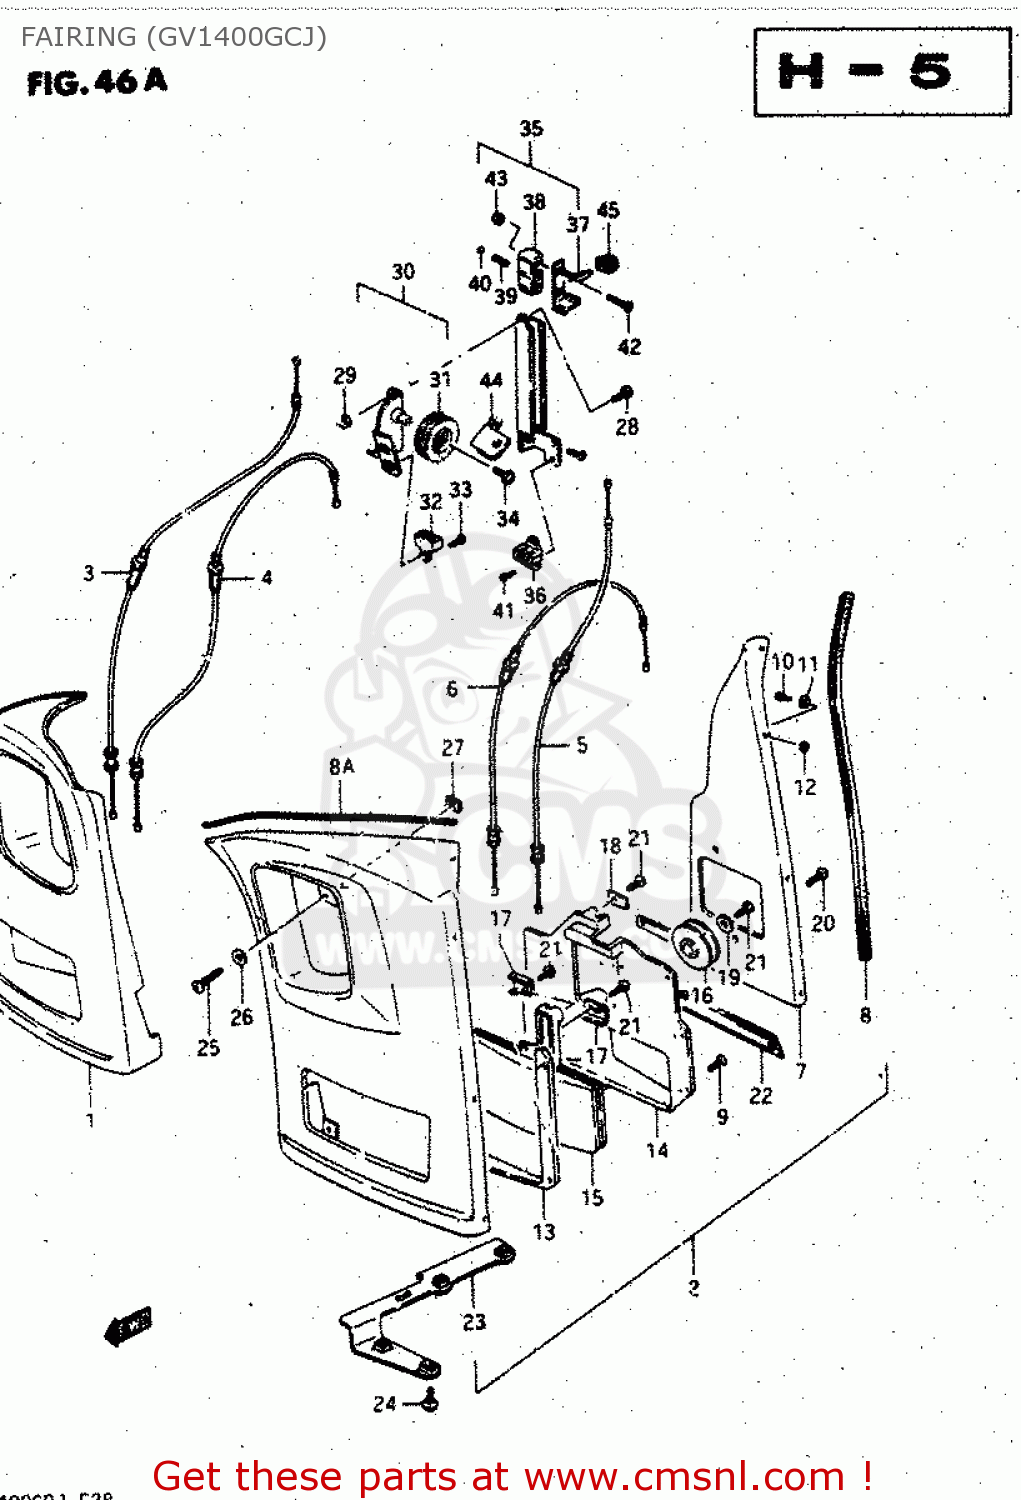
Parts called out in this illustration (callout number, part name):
1	FAIRING ASSEMBLY,EXTENSION
2	FAIRING ASSEMBLY,EXTENSION
3	CABLE COMP,VENTILATOR
4	CABLE COMP,VENTILATOR
5	CABLE COMP,VENTILATOR
6	CABLE COMP,VENTILATOR
7	EXTENTION, FAIRING REAR LH (BLACK)
8	MOLDING NO.1
8A	MOLDING, NO.2
9	SCREW
10	SCREW
11	WASHER
12	NUT
13	GUIDE,VENT LID NO.1
14	GUIDE, VENT LID NO.2 RH
15	LID, VENTILATOR RH (BLACK)
16	GUIDE,VENT CABLE
17	HOLDER, VENT CABLE RH
18	HOLDER, VENT CABLE CUTER
19	WASHER (4X16X1.2)
20	SCREW
21	SCREW
22	MOLDING, NO.3
23	BRACKET, EXTENTION RH
24	SCREW M5X12 DIN 7985/N
25	SCREW
26	WASHER (5.5X14X1.2)
27	NUT
28	BOLT 6X16
29	NUT 6MM
30	GUIDE ASSEMBLY,VENTILATOR
31	GUIDE, VENT CABLE
32	GUIDE, VENT OUTER CABLE
33	SCREW
34	SCREW M5X12 DIN 7985/N
35	OPERATION ASSEMBLY,VENTILATOR
36	GUIDE, VENT OUTER CABLE
37	LEVER, VENT OPERATION
38	SLIGER
39	SPRING
40	BALL
41	SCREW
42	SCREW
43	NUT
44	BRACKET COMP,VENT OPERATING
45	KNOB,VENTILATOR OPERATING
